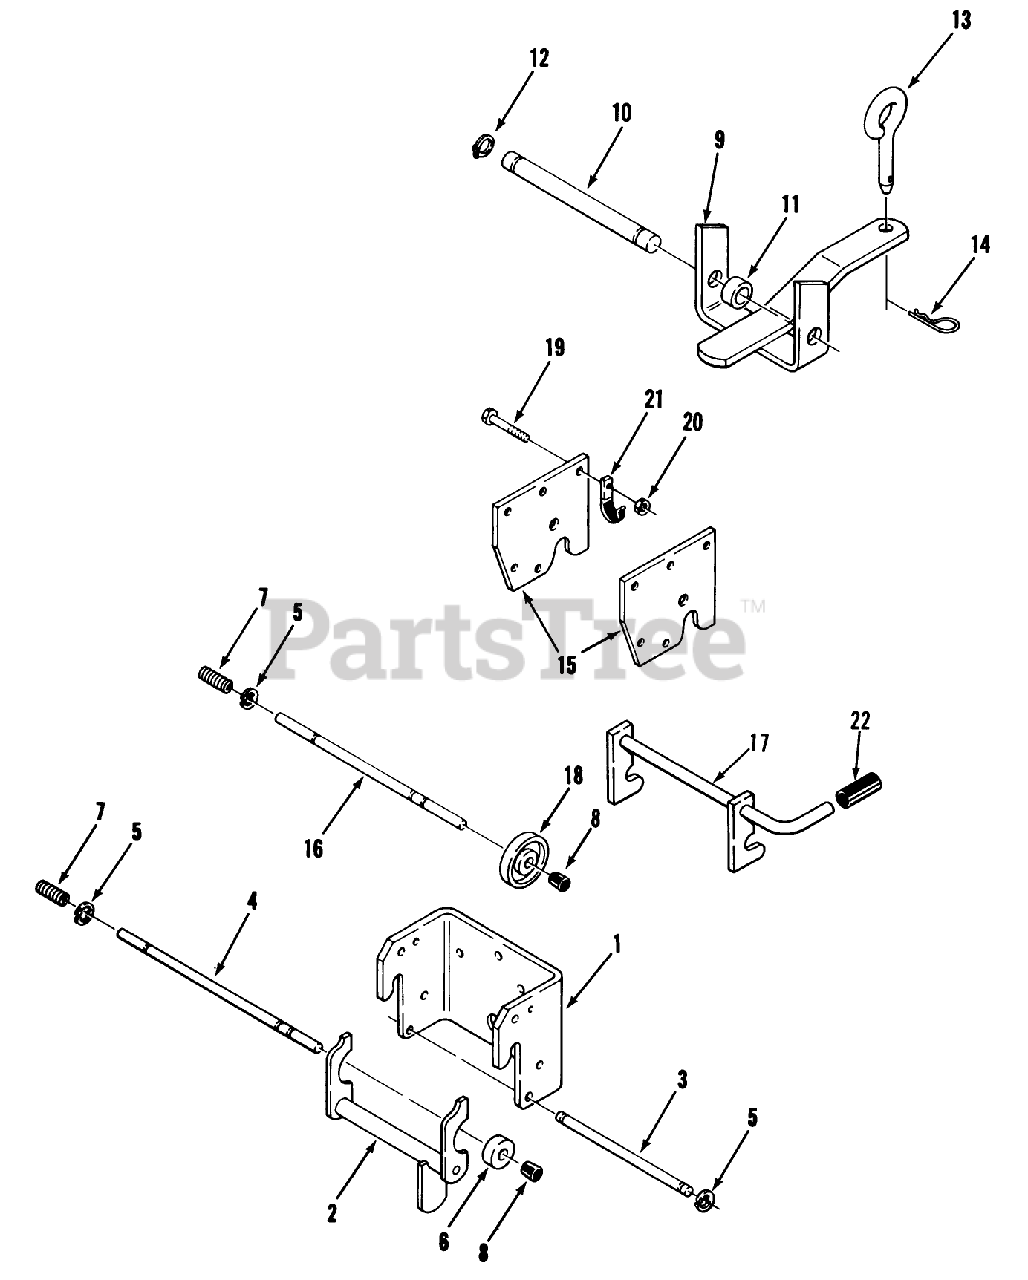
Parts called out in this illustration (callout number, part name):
3	ROD-LATCH PIVOT
4	ROD-LOCK
5	RING-RETAINING
7	SPRING
8	CAP-ROD, PLUNGER
10	PIN-STATIONARY HITCH
12	E-RING
13	PIN-TOOL
14	Hairpin Cotter
17	MID HITCH ASM
20	NUT-HEX
21	CLIP
22	GRIP
